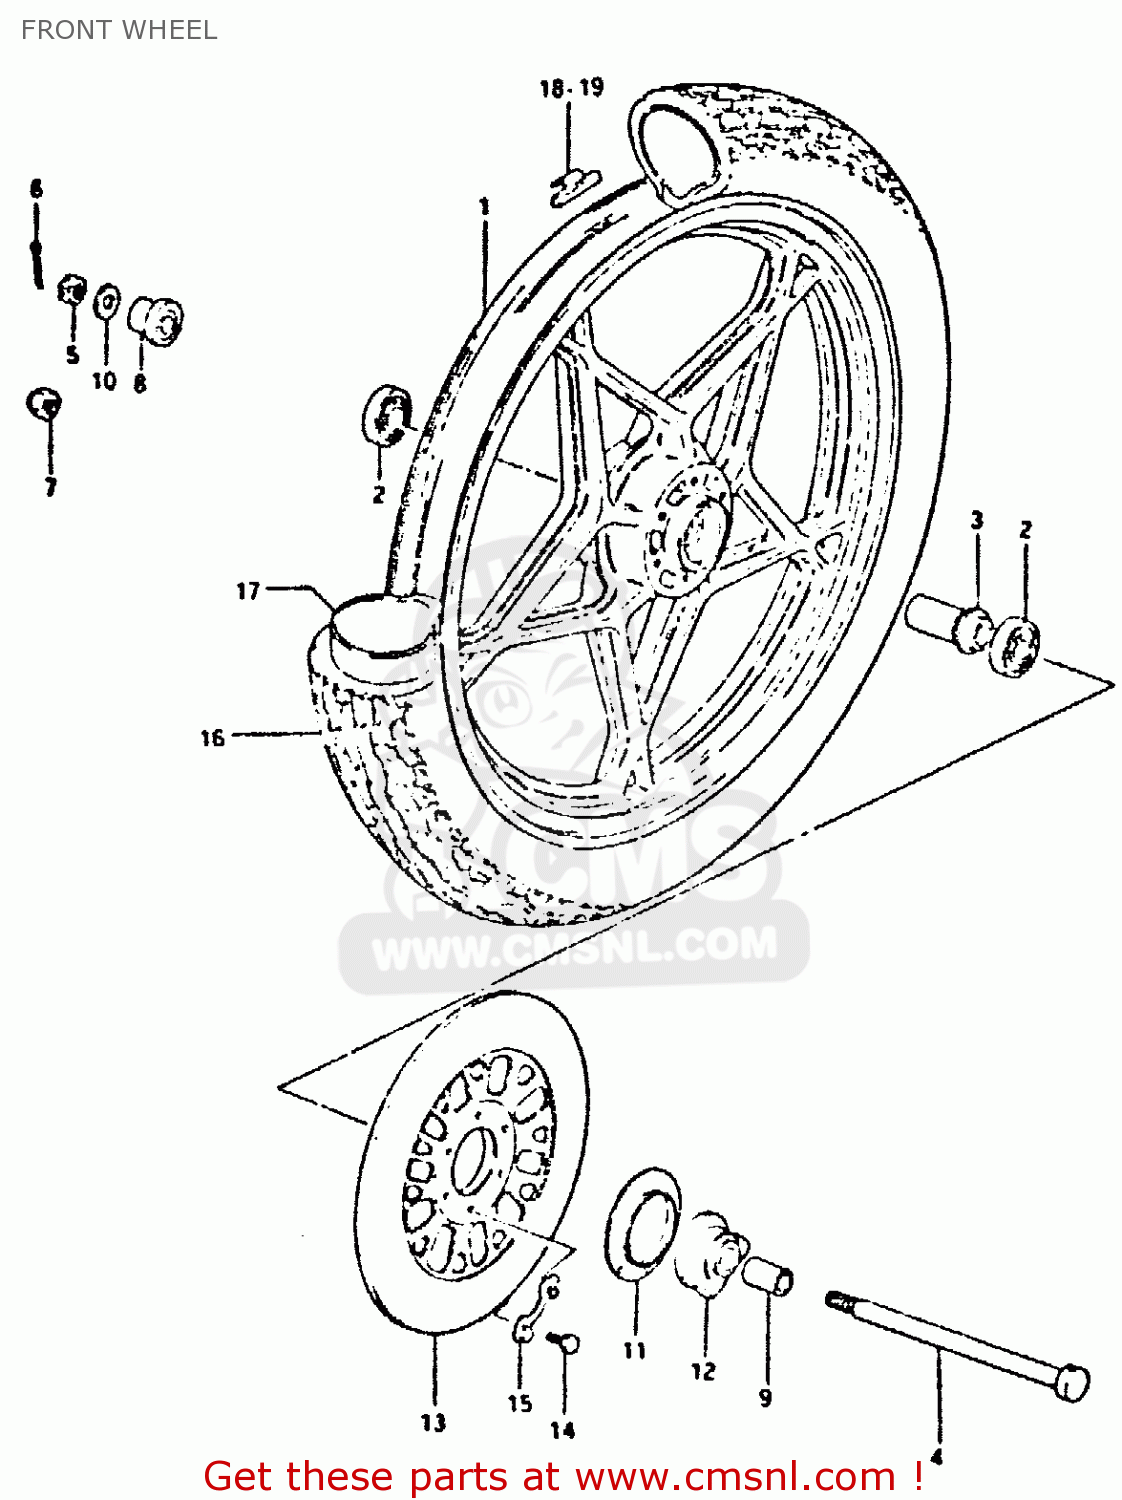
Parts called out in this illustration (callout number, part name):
1	WHEEL (GOLD)
2	BEARING
3	SPACER(15.3X21.7X63)
4	AXLE,FRONT
5	NUT 12MM
6	COTTER PIN
8	SPACER,FR HUB BEARING,R
9	SPACER(15X22X30)
10	WASHER
11	DUST SEAL,SPEEDOMETER GEAR BOX
12	BOX ASSY,SPEEDOMETER GEAR
13	DISC,FR BRAKE
14	BOLT(8X25)
15	WASHER
16	TIRE,FRONT
17	TUBE,INNER
18	BALANCER,WHEEL
19	BALANCER,WHEEL
